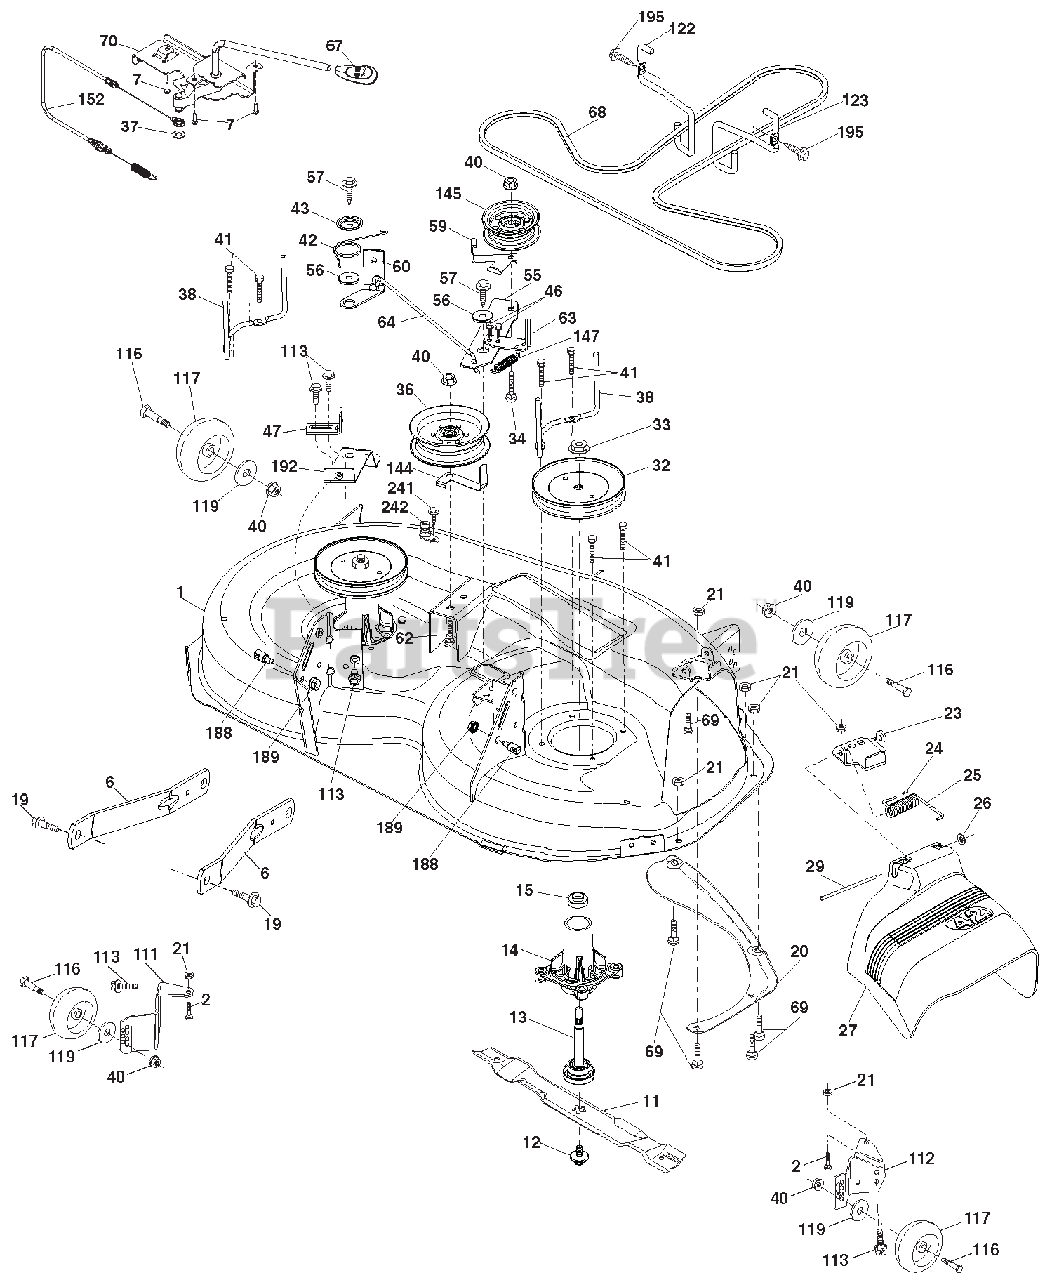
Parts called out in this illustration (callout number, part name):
1	DECK.PNT.WELDMENT.42"
6	ARM.SUSPENSION.MOWER.REAR.LD
11	BLADE.MOWER.42"HI LIFT PREMIUM
12	SCREW 7/16-20 X 1
13	SHAFT ASM
14	HOUSING.MANDREL.4PT.SERVICE
15	BEARING
19	BOLT.SHOULDER
20	BAFFLE.VORTEX.42.STD/HEAVY DTY
21	Nut, Hex, Crownlock 5/16-18
23	BRACKET.DEFLECTOR.38/42"2005
24	CAP.SLEEVE..80X.112.BLK.MOWER
25	SPRING.TORSION.DFL.38/42/46.GR
26	NUT.PUSH.PHOS.& OIL
27	SHIELD.DEFLECTOR.
29	ROD.HINGE.42/46"
32	PULLEY.MANDREL.5.438 PD.42"
32	MANDREL ASM
33	NUT.FLANGE.LOCK.TOP
34	BOLT.CARR.SH.3/8-16X1-1/2.GR5
36	PULLEY.IDLER.4.50.RAW
37	WASHER.13/32 X 13/16 X 16 GA.
38	KEEPER.BELT.MANDREL.PULLEY
40	Nut, Hex, Flangelock 3/8-16
41	HEX HEAD BOLT
42	SPRING.TORSION.BRAKE
43	SPRING.TORSION.RETAINER
46	SCREW.THD.ROLL.1/4-20 X 5/8
47	BRACKET.CLUTCH.CABLE
55	IDLER.ARM
56	SPACER.RETAINER
57	SCREW.3/8-16X1.SMGML.TAP/R.BLK
59	GUARD.TUV.IDLER
60	ARM.BRAKE.MOWER.42"
62	BOLT.RD.HD.SQ.NK.3/8-16UNC X 2
63	ARM.BRAKE.MOWER
64	LINKAGE.BRAKE
67	HANDLE.CLUTCH.CABLE.LT TEX.428
68	BELT.DRIVE.100.97"
69	BOLT.RDHD.SQNK.5/16-18 X 5/8
70	CLUTCH ASM.
111	BRACKET WHEEL GAUGE LH
112	BRACKET WHEEL GAUGE RH
113	BOLT.5/16-18HEX.WHS.HD.LCKSERR
116	BOLD SHLD "A" 2.41 "B" 1.66
117	WHEEL.GAGE.HALF.SPOKED
119	Washer 3/8 x 7/8 x 14 Ga.
122	KEEPER.BELT.ENGINE.LH.LT.TEX
123	KEEPER.BELT.ENGINE.RH.LT.TEX
144	KEEPER.BELT.MOWER
145	PULLEY.IDLER 48"PRIMARY
147	SPRING.RETURN
152	CABLE.CLUTCH.MANUAL
188	STUD.FASTNER.W/'D'ANTI-ROTATIO
189	Nut, Lock Hex Flange 5/16-18 u
192	BRACKET.BRAKE.STAND.LH
195	SCREW.5/16-18X3/4.SMGML.TAP/BL
242	PORT WASHOUT
